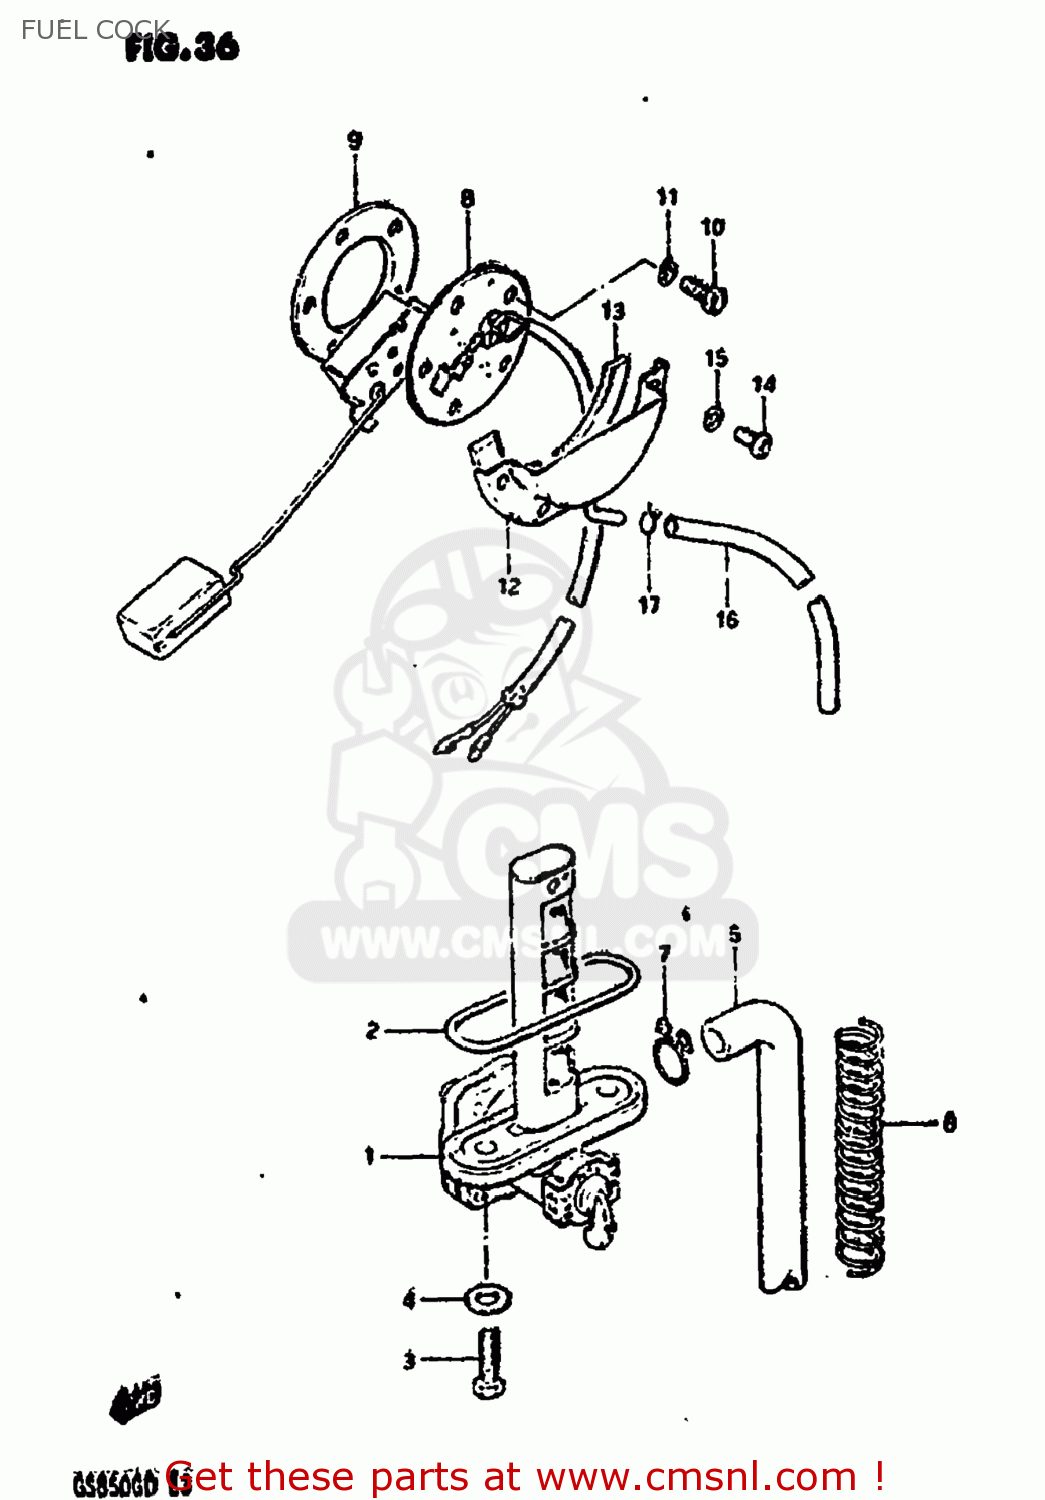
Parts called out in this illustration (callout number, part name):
1	COCK ASSEMBLY,FUEL
2	O RING
3	BOLT(6X20)
4	GASKET
5	HOSE
6	SPRING
7	CLIP
8	GAUGE ASSEMBLY,FUEL LEVEL
9	GASKET,FUEL LEVEL GAUGE (NAS)
10	BOLT
11	LOCK WASHER
12	PLATE,FUEL DRAIN
13	GASKET (NAS)
14	SCREW
15	LOCK WASHER
16	HOSE,FUEL
17	CLIP
